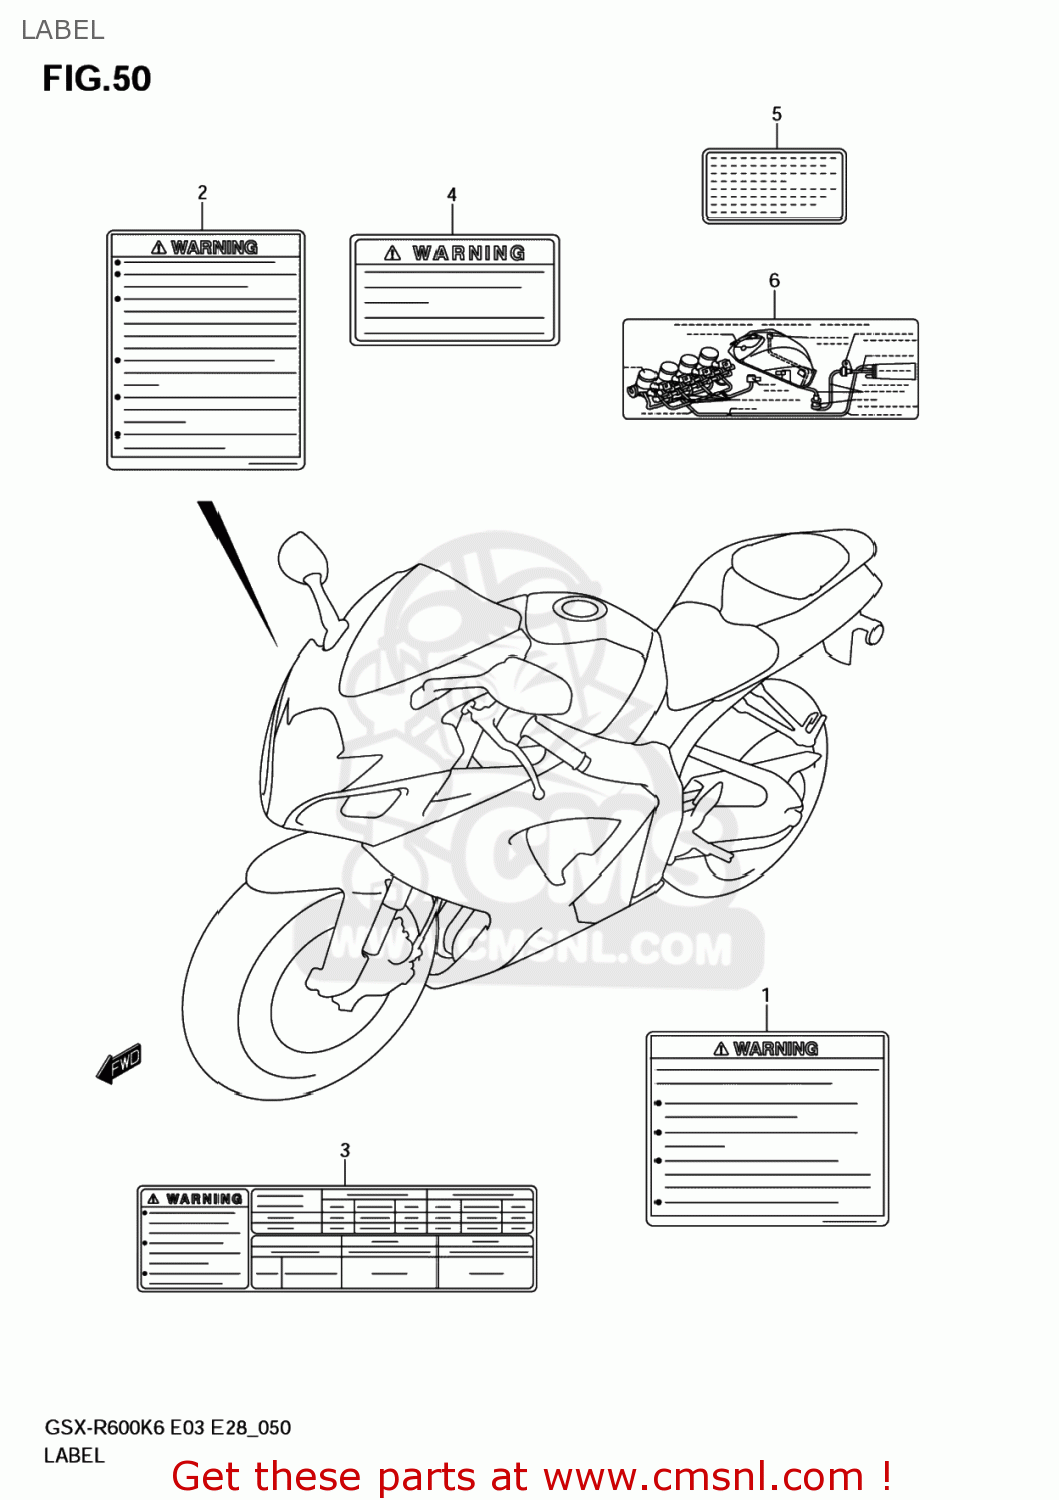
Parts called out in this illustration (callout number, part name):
1	LABEL,GENERAL WARNING
2	LABEL,SCREEN
3	LABEL,TIRE INFORMATION
4	LABEL,WARNING STEERING
5	LABEL,MANUAL NOTICE
6	LABEL,VACUUM HOSE ROUTING
7	MANUAL,OWNER'S
